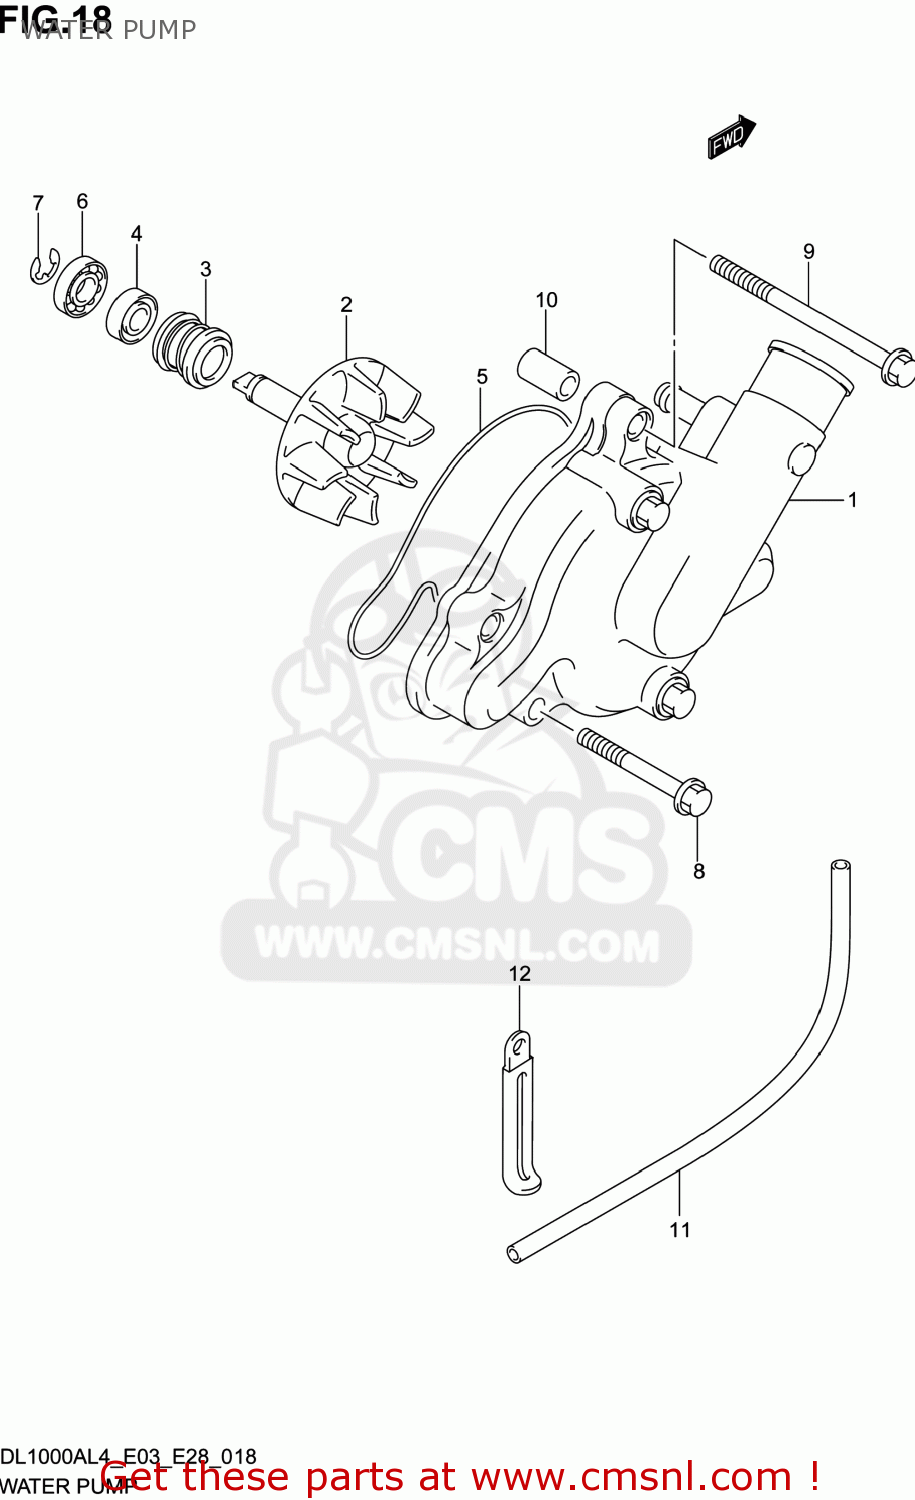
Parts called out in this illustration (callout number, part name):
1	CASE,WATER PUMP
2	IMPELLER,WATER PUMP
3	SEAL,MECHANICAL
4	SEAL,OIL(10X20X5)
5	O RING,WATER PUMP CASE
6	BEARING(10X22X5)
7	E RING
8	BOLT(6X30)
9	BOLT(6X65)
10	PIN
11	HOSE(4.2X7X600)
12	CLAMP(L:45)
